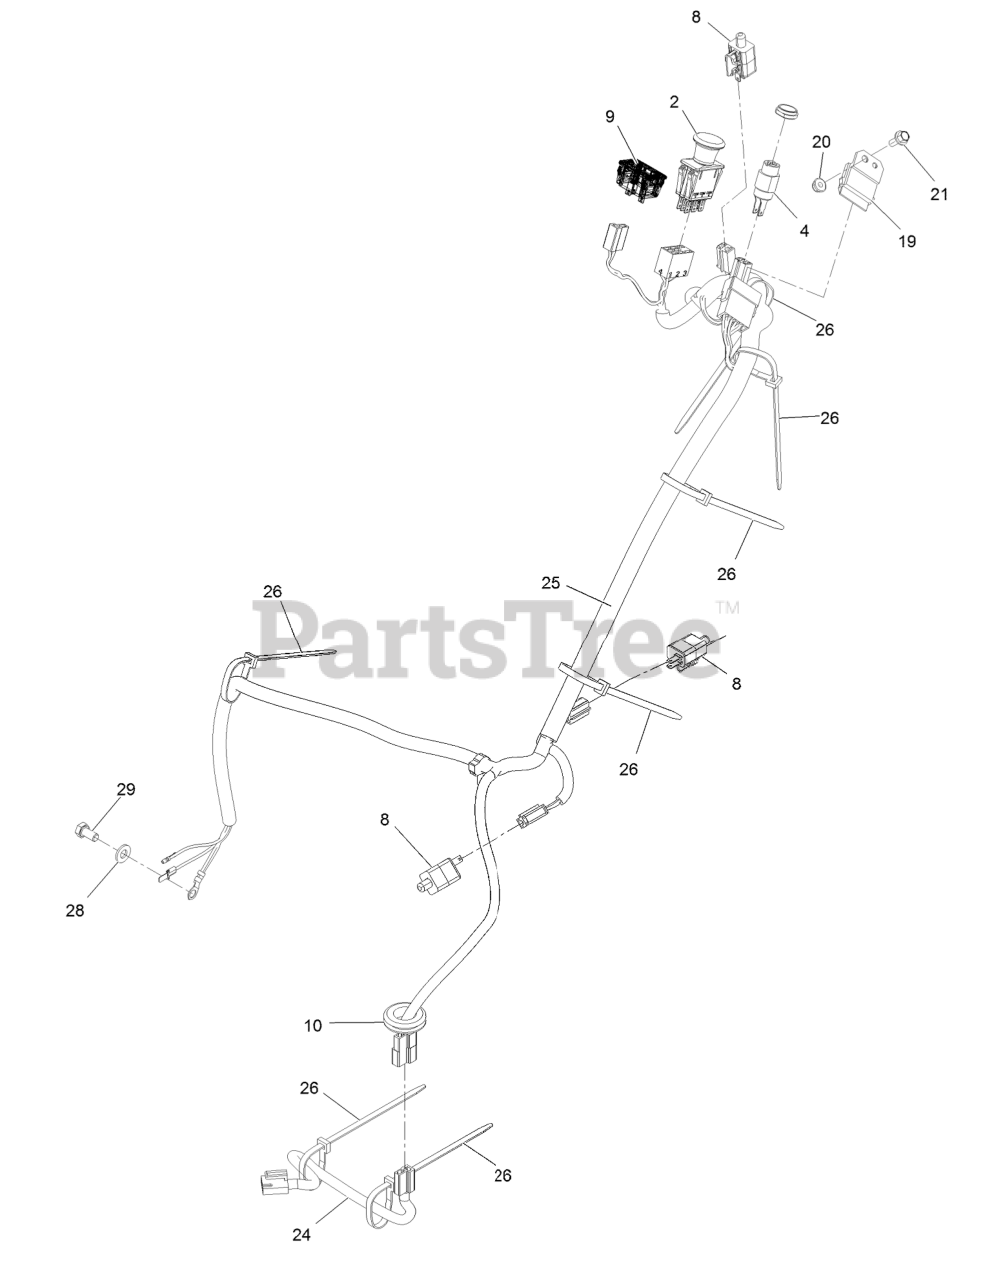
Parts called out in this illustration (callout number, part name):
2	SWITCH-PTO
4	SWITCH & KEY (INCLUDES NU
4	NUT-SWITCH, IGNITION
9	METER-HOUR
10	GROMMET
19	MODULE-INTERLOCK
21	SCREW-HHF
24	HARNESS-CLUTCH PIGTAIL
25	HARNESS-MAIN
26	TIE-PLASTIC
28	WASHER-PLAIN
29	SCREW-HH
